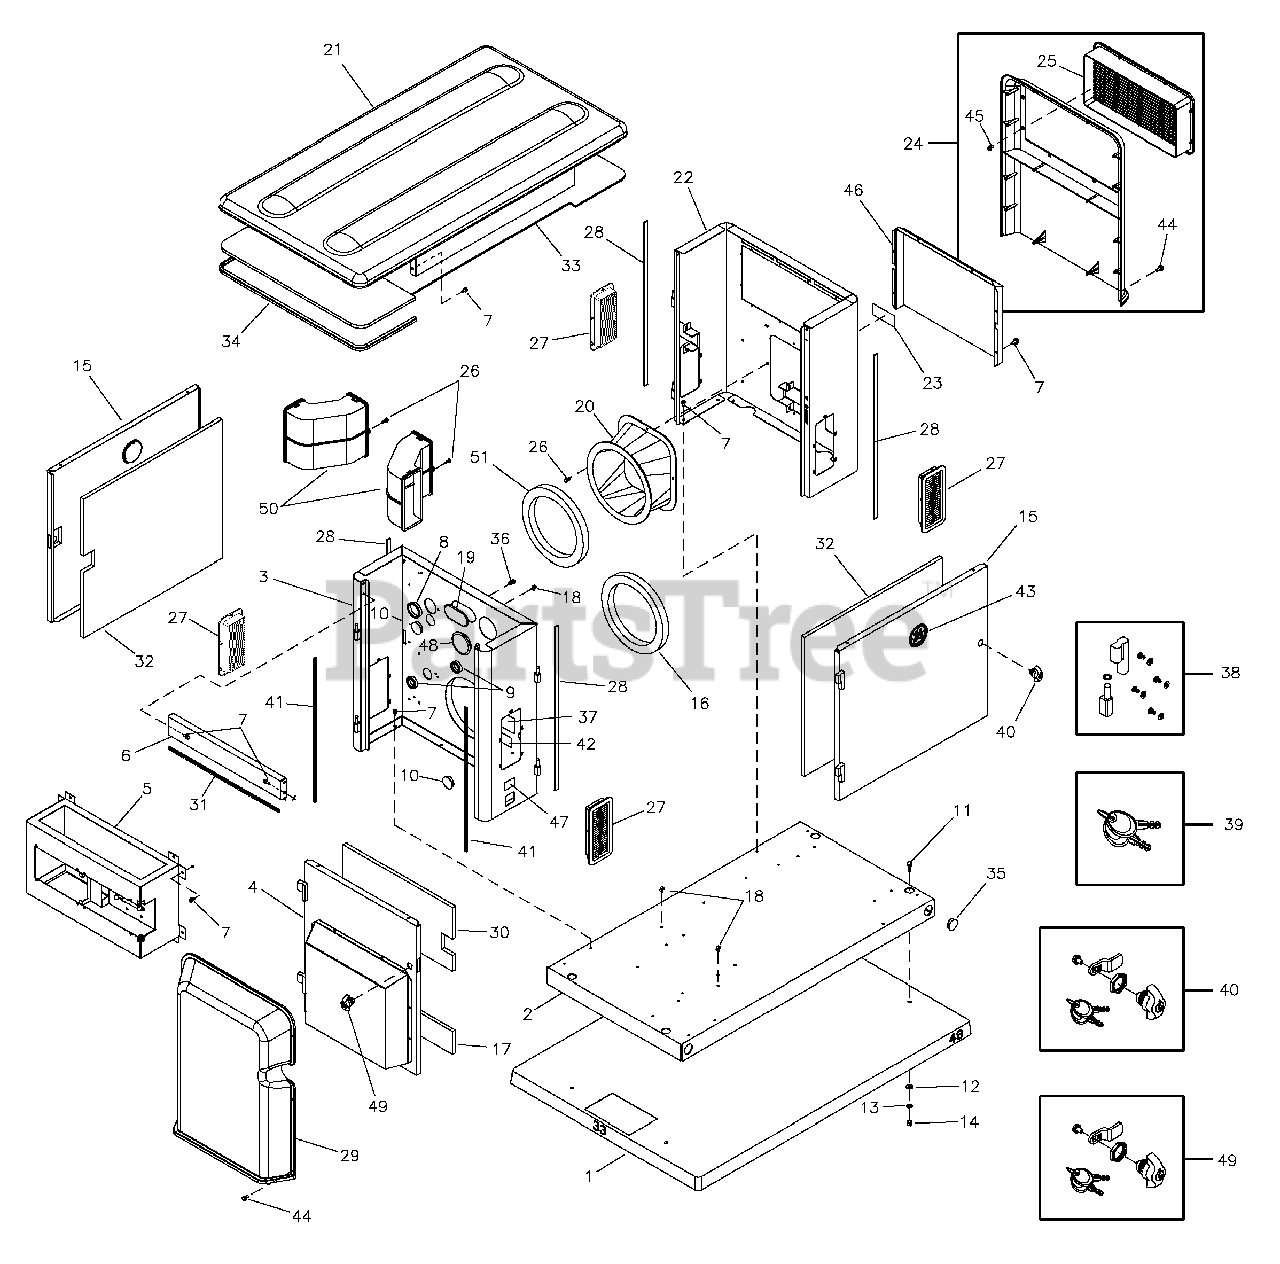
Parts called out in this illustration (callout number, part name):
3	BULKHEAD, Engine
7	BOLT
11	* WASHER, Flat, 3/8-M10
13	* WASHER, Lock, 3/8
14	* NUT, 3/8-16
20	ADAPTER, Alternator
22	BULKHEAD, Alternator
42	DECAL
44	SCREW
47	DECAL, Fuel Inlet
